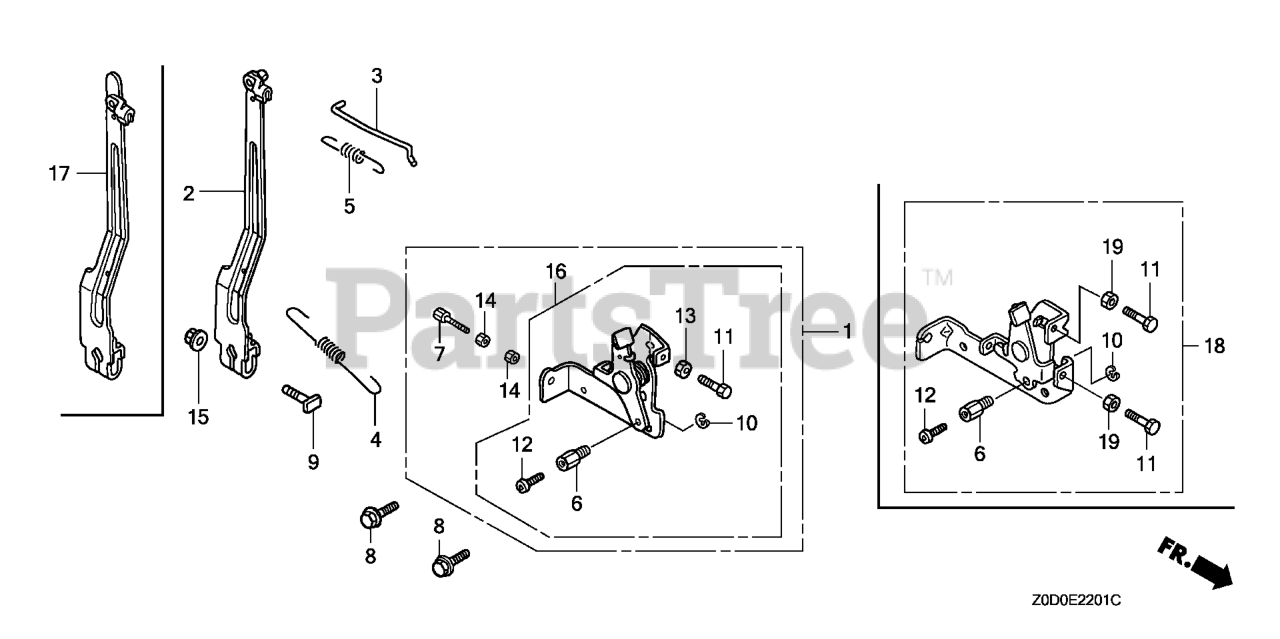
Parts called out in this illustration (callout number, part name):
1	CONTROL ASSY.
3	ROD, GOVERNOR
4	SPRING, GOVERNOR
5	SPRING, THROTTLE RETURN
6	HOLDER, WIRE
7	BOLT, CABLE ADJUSTING (6X34)
8	BOLT, FLANGE (6X14)
9	BOLT, GOVERNOR ARM
10	CIRCLIP (5MM) Use from Engine SN 2327377.
11	BOLT, HEX. (5X20)
12	SCREW, PAN (4X6)
13	NUT, HEX. (5MM)
14	NUT, HEX. (6MM)
15	NUT, FLANGE (6MM)
17	ARM, GOVERNOR
